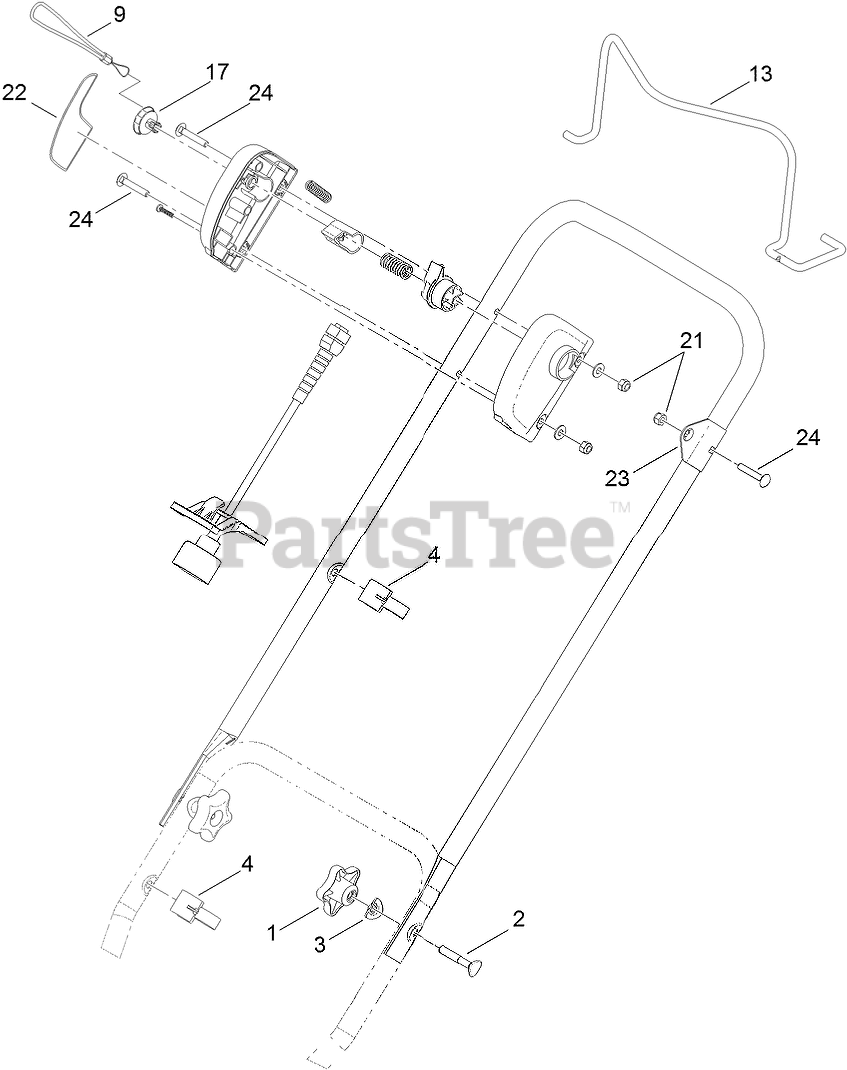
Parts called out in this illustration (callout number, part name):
1	KNOB-HANDLE
2	SCREW-HANDLE
3	WASHER
4	GUIDE-CABLE
9	CORD-KEY
17	KEY-BAIL
21	NUT-LOCK, NI
22	DECAL-OPERATION
23	BRACKET-BAIL
24	SCREW-CARR
